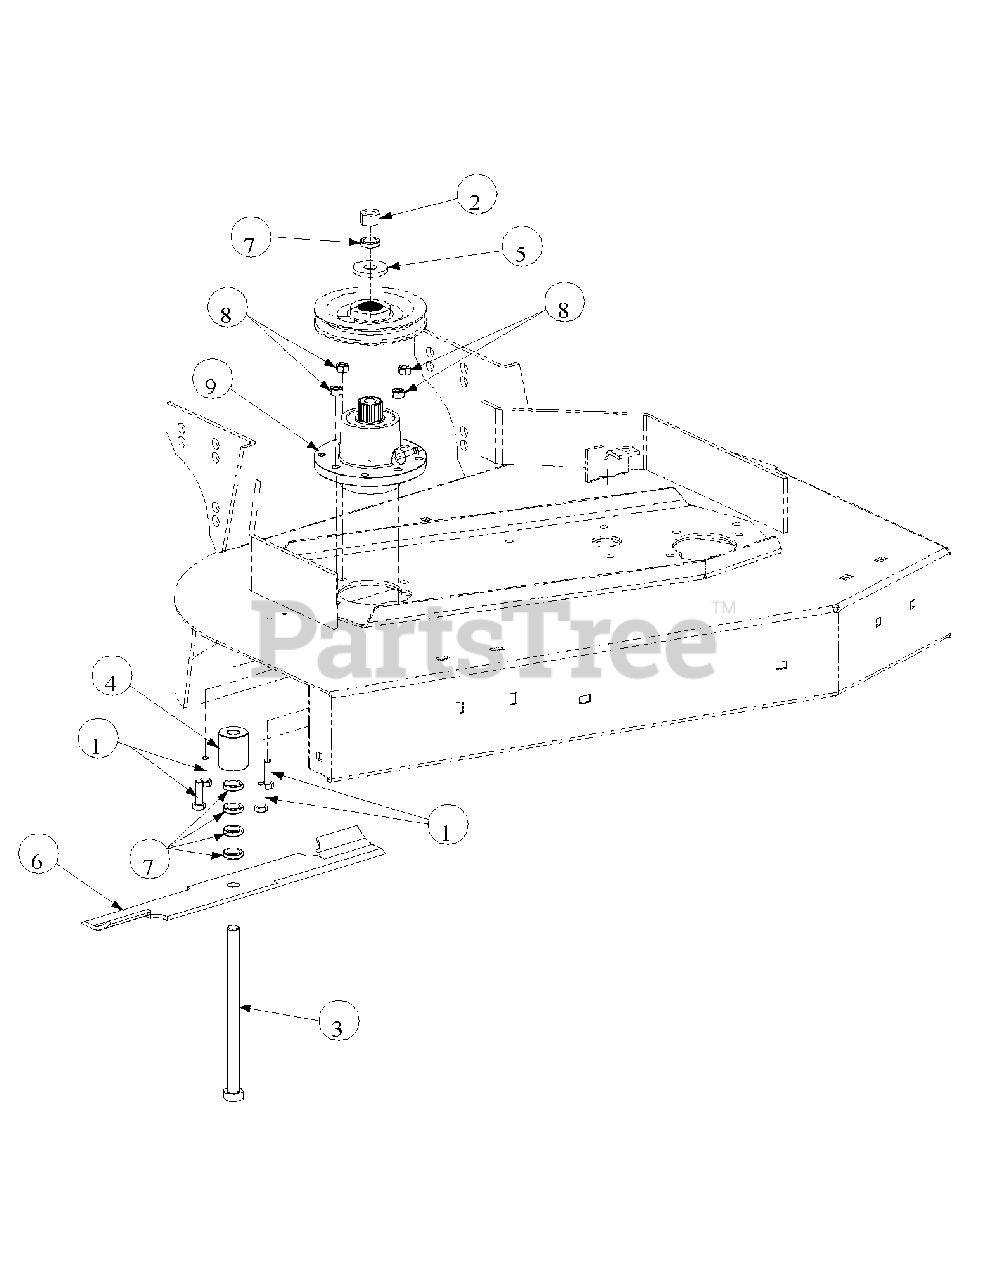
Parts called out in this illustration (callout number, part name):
1	Hex Cap Screw, 3/8-16 x 1-1/4
2	Hex Nut, 5/8-11
3	Hex Cap Screw, 5/8-11 x 9
4	Blade Spacer, .630 x 1.500 x 1.850
5	Flat Washer, .656 ID x 1.313 OD
6	16 1/2" Rotary Blade
7	Blade Spacer, 5/8 ID, 1/4 Thick
8	Lock Nut, 3/8-16
9	Spindle Assembly
